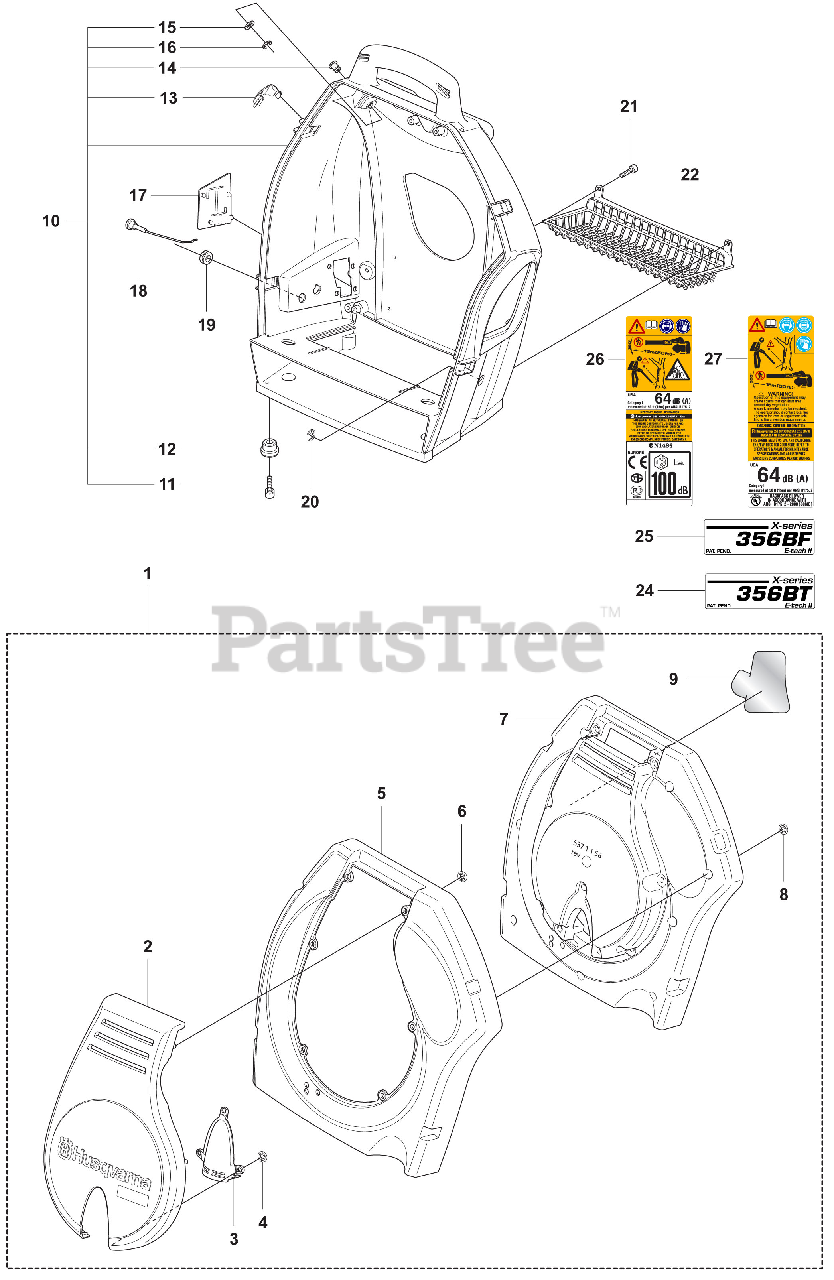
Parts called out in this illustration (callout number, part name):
4	LOCKING WASHER
6	LOCKING WASHER
7	INSULATION **
8	LOCKING WASHER
13	BUCKLE ORANGE
14	SLEEVE, CHASSIS
16	RETAINING RING
17	COVER
18	CHOKE CONTROL
20	E-RING
24	DECAL
25	DECAL
26	ROW ONLY
